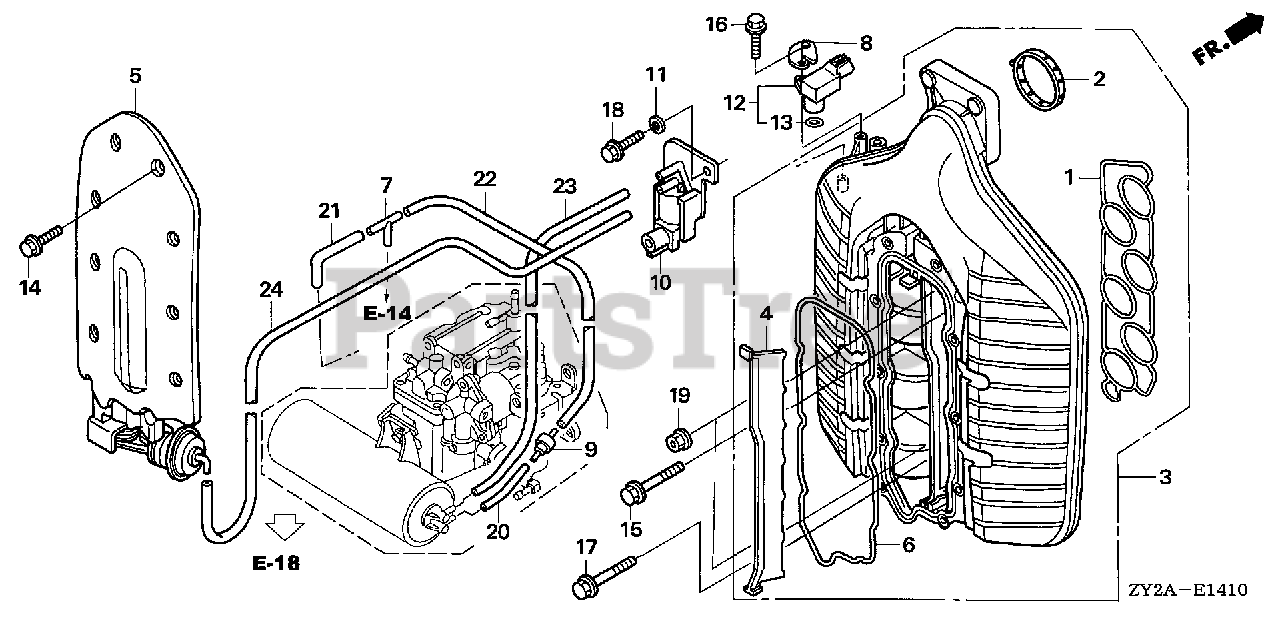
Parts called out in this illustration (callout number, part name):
1	GASKET, IN. MANIFOLD
2	GASKET, THROTTLE BODY
3	MANIFOLD, IN.
4	PLATE, IN. MANIFOLD CENTER
5	COVER, IN. MANIFOLD *NH8* (DARK GRAY)
6	GASKET, IN. MANIFOLD UP COVER
7	JOINT A, VACUUM TUBE
8	BRACKET, SENSOR WIRE
9	VALVE, CHECK
10	VALVE ASSY., AIR BYPASS
11	WASHER, CONICAL SPRING (5)
12	SENSOR ASSY., MAP
14	BOLT, FLANGE (6X22)
15	BOLT, FLANGE (8X50)
16	BOLT-WASHER (5X18)
17	BOLT, FLANGE (6X32)
18	BOLT, FLANGE (5X10)
19	NUT, FLANGE (8MM)
20	BULK HOSE, FUEL (3.5X3000) (3.5X40)
21	BULK HOSE, FUEL (3.5X3000) (3.5X130)
22	BULK HOSE, FUEL (3.5X3000) (3.5X540)
23	BULK HOSE, FUEL (3.5X3000) (3.5X590)
24	BULK HOSE, FUEL (3.5X3000) (3.5X600)
